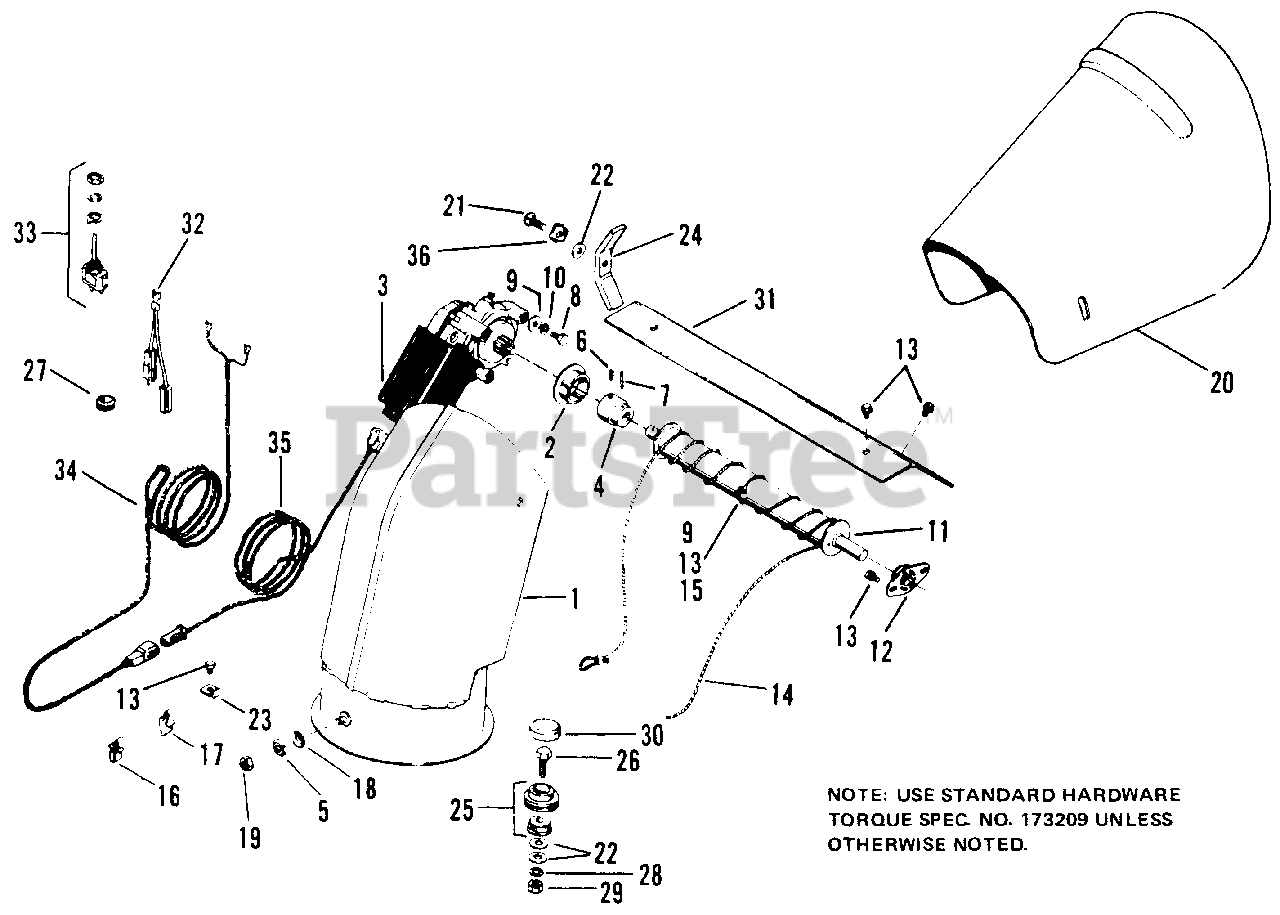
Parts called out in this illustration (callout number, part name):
1	SPOUT ASSY
2	BEARING, Flange
3	MOTOR, Spout Control
5	WASHER, Cup
6	SCREW, Hex, Skt. Hd., Cup Pt., No. 10-24 x 3/8, Gr. 8
7	PIN, Spring, 5/32 x 1
8	CAPSCREW, Hex Hd., 1/4-20 x 3/4
9	WASHER, Plain, 1/4
10	LOCKWASHER, Spring, 1/4
11	TUBE ASSY, Spout Control
13	SCREW, Hex, Wshr. Hd., Taptite, 1/4-20 x 3/8
14	CABLE ASSY
16	CLIP, Cable
17	CLIP, Cable
18	WASHER, Cup
19	NUT, Hex, Lock, 5/16-18
20	EXTENSION, Spout
21	BOLT, Rd. Hd., Sh. Sq. Nk., 3/8-16 x 3/4
22	WASHER, Plain, 3/8
23	CLIP, Cable
24	NUT, Wing
25	PULLEY & BEARING ASSY
26	CAPSCREW, Hex Hd., 3/8-16 x 1-1/4
27	GROMMET, Rubber
28	LOCKWASHER, Spring, 3/8
29	NUT, Hex, 3/8-16
31	COVER, Chute Control
32	WIRE, Chute (Control Switch to Ignition Switch)
33	SWITCH, Spout Control
34	HARNESS ASSY, Switch
35	HARNESS ASSY, Motor
36	LOCKWASHER, Pyramidal Type, 3/8
